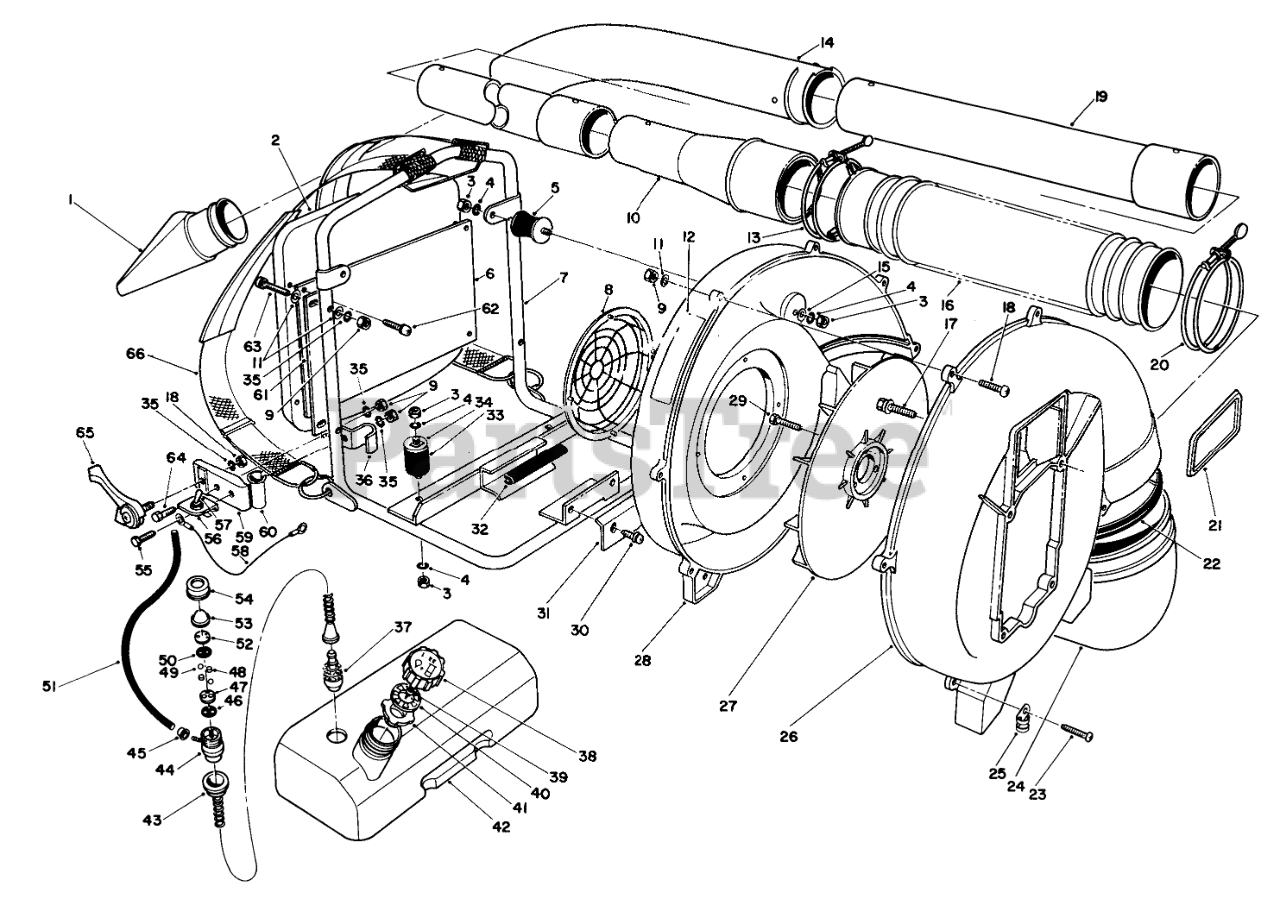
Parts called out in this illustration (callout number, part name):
1	NOZZLE
4	WASHER SPRING
5	CUSHION RUBBER
6	PLATE
7	FRAME
8	FAN COVER
11	WASHER
12	Decal-Warning
13	WIRE BAND
15	WASHER
17	BOLT & WASHER
18	SCREW & WASHER
20	WIRE BAND
21	TORO LOGO PLT
22	DUST SEAL RING
23	SCREW
24	ELBOW
25	Clamp
26	FAN CASE
28	FAN CASE
29	BOLT ? WASHER
30	BOLT & WASHER
31	STOPPER
32	CUSHION RUBBER
33	CUSHION RUBBER
34	CUSHION HOLDER
35	SPRING WASHER
36	STOPPER
37	FUEL FILTER
38	TANK CAP
39	BREATHER VALVE
40	HOLDER
41	GASKET - PACKING
42	Fuel Tank Assembly (Incl. Ref. #37-41, 43, 44, 46-50, & 52-54)
43	HOSE, SUCTION
44	Pump-Primer (Incl. Ref. #47-54)
46	GASKET
47	SEAT VALVE
48	SPONGE
50	GASKET
51	FUEL TUBE
52	SEAT VALVE
54	PUMP CAP
56	SWITCH BRACKET
57	STOP SWITCH
58	WIRE LEAD
59	BRACKET
60	BUSHING
61	PLATE
62	SCREW & WASHWER
63	SCREW & WASHER
65	THROTTLE LEVER
66	SHOULDER HARNESS
